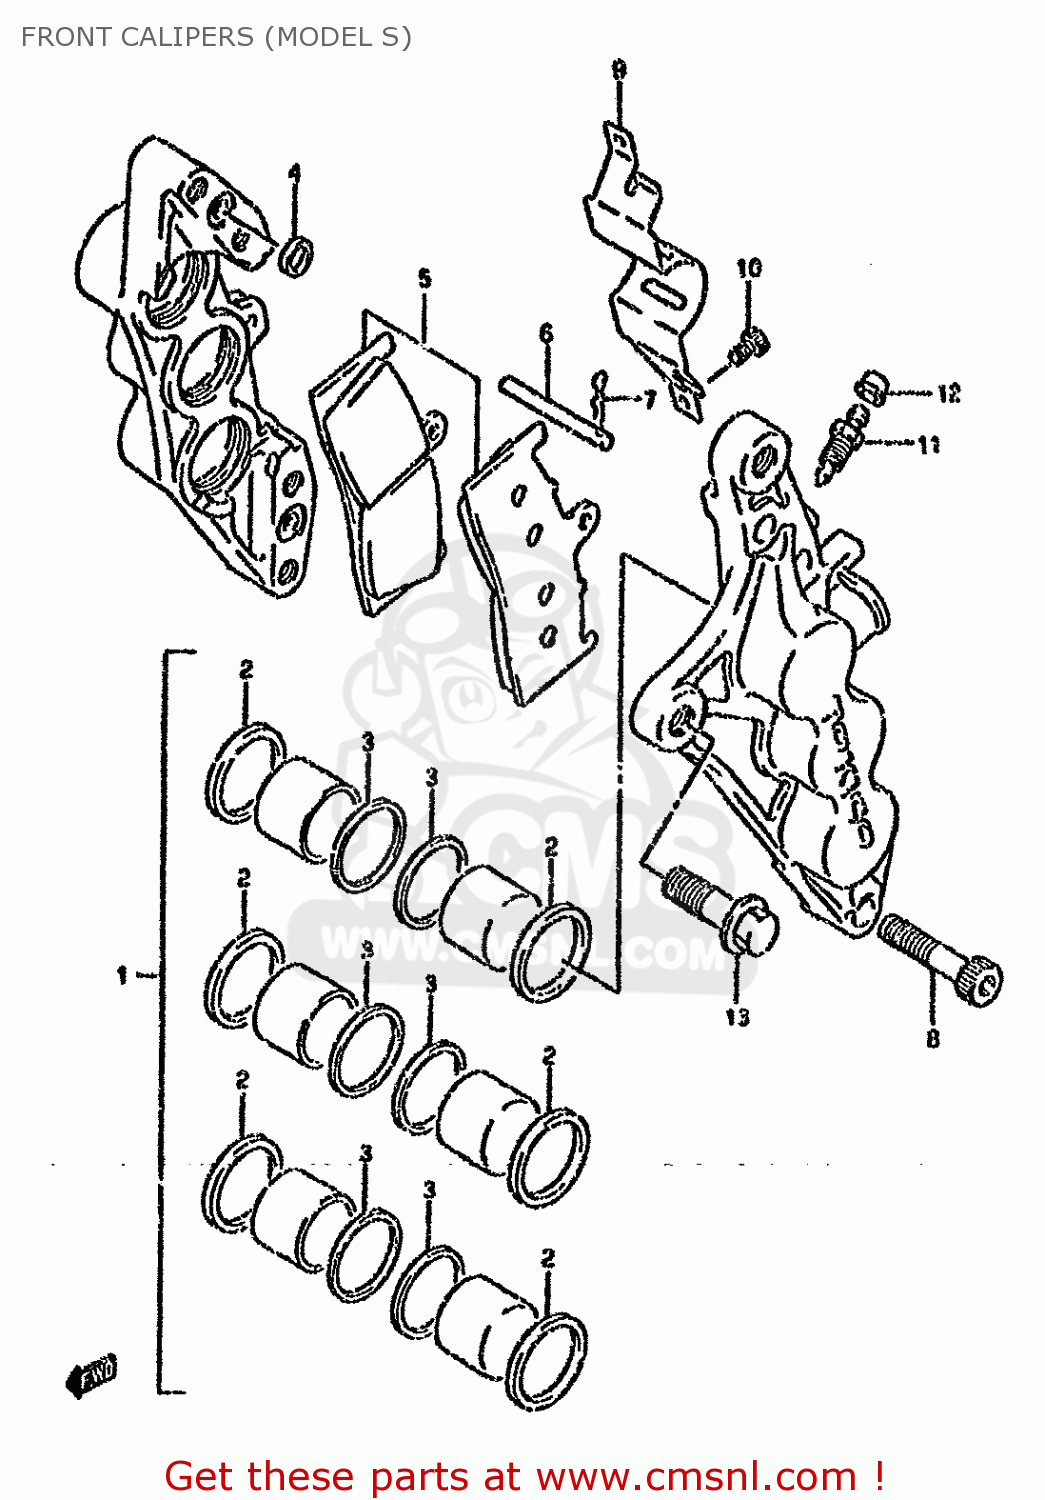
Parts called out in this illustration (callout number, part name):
1	PISTON SET
2	SEAL,PISTON
3	SEAL,WIPER
4	SEAL,JOINT
5	PAD SET (NAS)
6	PIN,PAD
7	CLIP,PAD PIN
8	BOLT,CALIPER
9	COVER,CALIPER
10	SCREW
11	BLEEDER
12	CAP,BLEEDER PLUG
13	BOLT
14	BOLT
